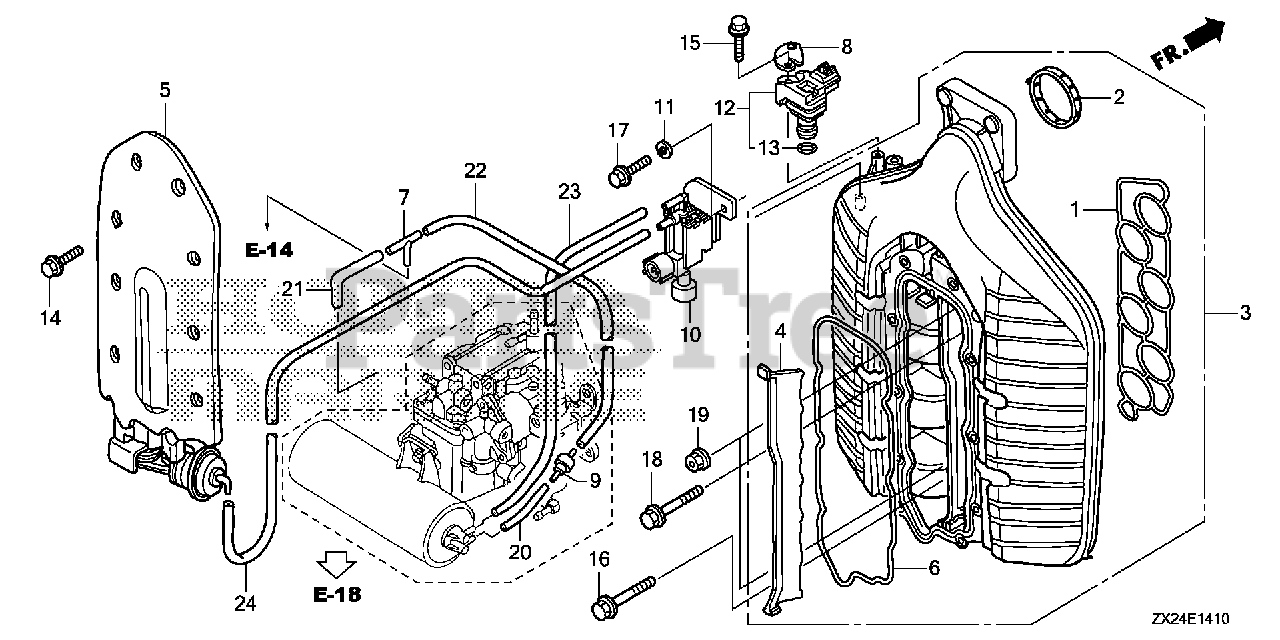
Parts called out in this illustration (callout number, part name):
1	GASKET, IN. MANIFOLD
2	GASKET, THROTTLE BODY
3	MANIFOLD, IN.
4	PLATE, IN. MANIFOLD CENTER
5	COVER, IN. MANIFOLD *NH8* (DARK GRAY)
6	GASKET, IN. MANIFOLD UP COVER
7	JOINT A, VACUUM TUBE
8	BRACKET, SENSOR WIRE
9	VALVE, CHECK
10	VALVE ASSY., AIR BYPASS
11	WASHER, CONICAL SPRING (5)
12	SENSOR ASSY., MAP
14	BOLT, FLANGE (6X22)
15	BOLT-WASHER (5X18)
16	BOLT, FLANGE (6X32)
17	BOLT, FLANGE (5X10)
18	BOLT, FLANGE (8X50)
19	NUT, FLANGE (8MM)
20	BULK HOSE, FUEL (3.5X3000) (3.5X40)
21	BULK HOSE, FUEL (3.5X3000) (3.5X130)
22	BULK HOSE, FUEL (3.5X3000) (3.5X540)
23	BULK HOSE, FUEL (3.5X3000) (3.5X590)
24	BULK HOSE, FUEL (3.5X3000) (3.5X600)
